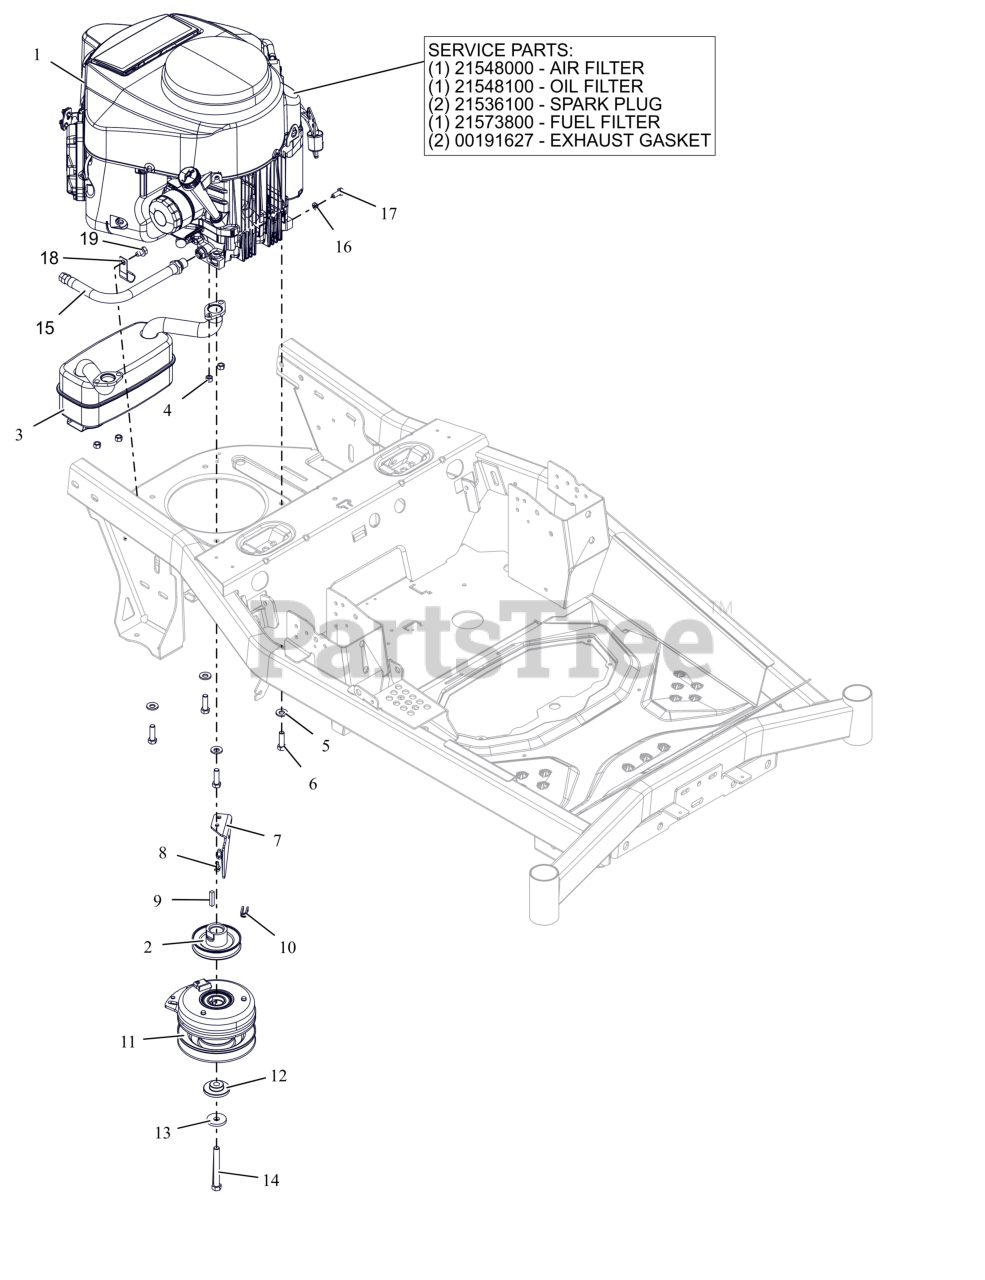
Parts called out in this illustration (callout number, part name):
1	ENGINE, KAWASAKI FR651V
1	AIR FILTER, KAWASAKI FR
1	OIL FILTER, KAWASAKI FR
1	PLUG, SPARK
1	FUEL FILTER
1	GASKET, MUFFLER S/O
2	WLDMT-PULLEY-4.831OD X1.003
3	MUFFLER - KAWASAKI
4	NUT-LK-TOP-FLG M8 ZCC
5	WASHER, 3/8" SPRING DISC
6	BLT, HEX .38-16X1.25 G5 ZCC NT
7	BRKT- CLUTCH STOP
8	SCR-TAP .25-20X.50 HWH ZCC
9	KEY-SQ .25 X 1.25 X .25 SAE
10	BSHG, CLUTCH
11	CLUTCH, WARNER-IXR-18211
12	BSHG-FLG .469X1.06X.574X2.0
13	WASHER, 7/16" SPRING DISK
14	BLT- HEX .44-20X3.50 G8 ZCC NT
15	HOSE, OIL DRAIN
16	WSHR,LK-REG .312X.078 ZCC
17	BLT, HEX M8-1.25X20 G8.8 ZCC
19	SCR,TAP .375-16X.50 HWH TR ZCC
